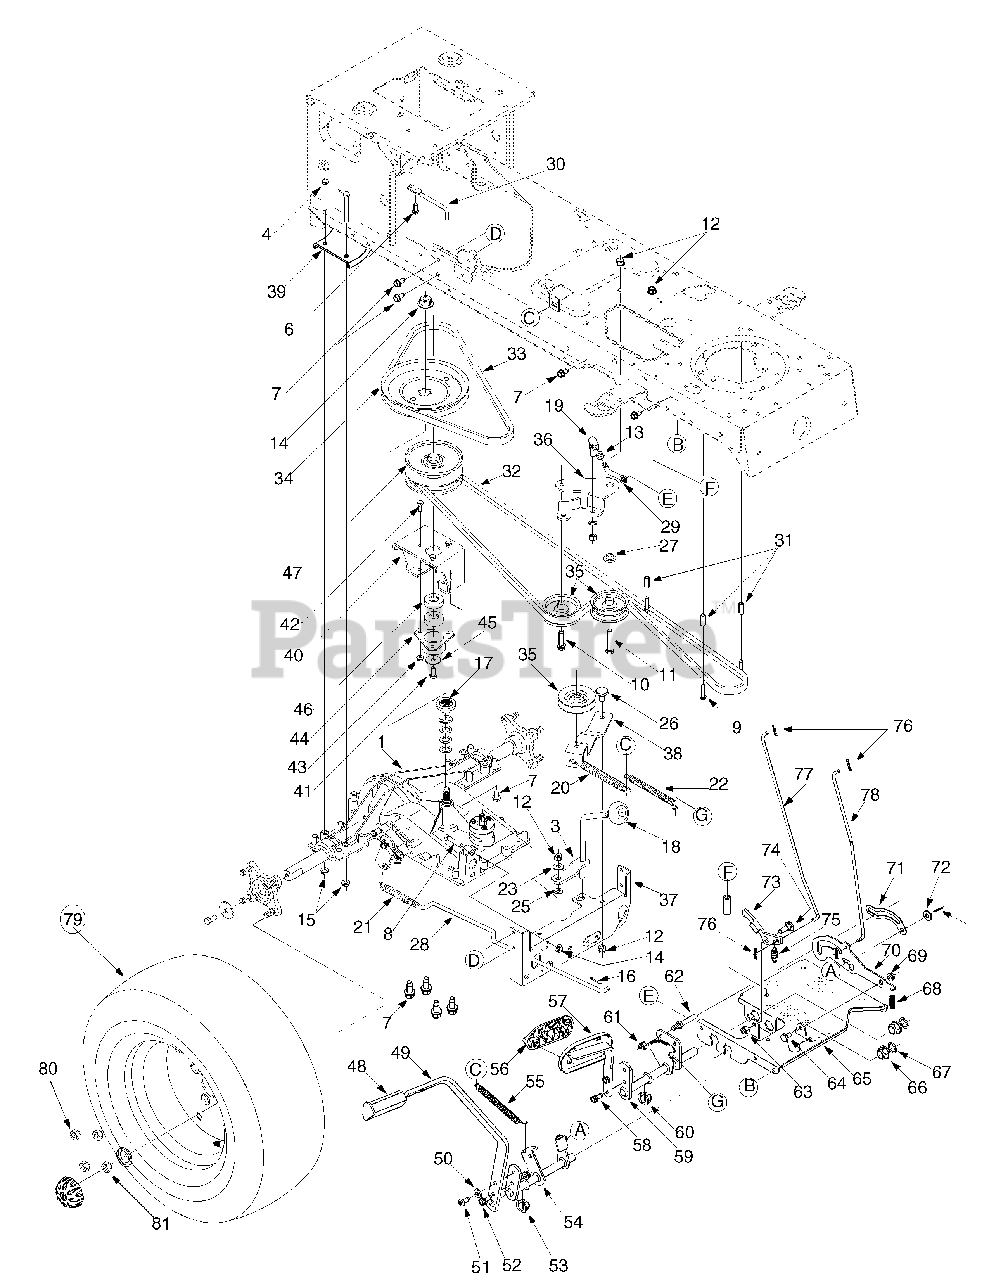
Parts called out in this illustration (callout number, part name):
1	Transmission Assembly
3	Shift Rod Assembly
4	Hex Bolt 5/16-18 x 2.75
6	TT Screw 1/4-20 x 0.75
7	AB Screw 5/16-12 x 0.75
8	Hex Bolt 5/16-18 x 1.5
9	TT Screw 1/4-20 x 1.25
10	TT Sems Screw 3/8-16 x 1.5
11	Hex Bolt 3/8-16 x 2.25
12	Lock Nut 3/8-16
13	Hex Nut 3/8-24
14	Flanged Nut
15	Flanged Lock Nut
16	Cotter Pin
17	Pulley Hub
18	Shift Knob
19	Ball Joint
20	Extension Spring
21	Extension Spring
22	Extension Spring
23	Bell Washer
25	Flat Washer
26	Shoulder Screw
27	Shoulder Spacer
29	Rod: Idler Adjustment
30	Rod: Belt Guard
32	Belt: V Type
33	Belt: V Type
34	Pulley
35	Idler Pulley, Flat
42	Hex Bolt 1/4-20 x 0.75
43	Flanged Lock Nut
44	Cup: Bearing
45	Flat Washer
46	Ball Bearing
47	Variable Speed Pulley
48	Brake Pad
51	TT Screw 5/16-18 x 0.75
52	TT Screw 5/16-18 x 0.875
53	Hex Flange Bearing: Split
54	Brake Control Assembly
55	Extension Spring
56	Control Pad
57	Drive Pedal Assembly
58	LD Screw 5/16-18 x 0.75
62	Pin
64	Shoulder Screw
66	Hex Flange Bearing
67	Push Nut
68	Compression Spring
69	Flange Lock Nut
70	Lock-Out Bracket
72	Flat Washer
73	Cruise Latch
74	Shoulder Screw
75	Extension Spring
76	Cotter Pin
77	Brake Lock Rod
78	Cruise Control Rod
80	Lug Nut 7/16-14
